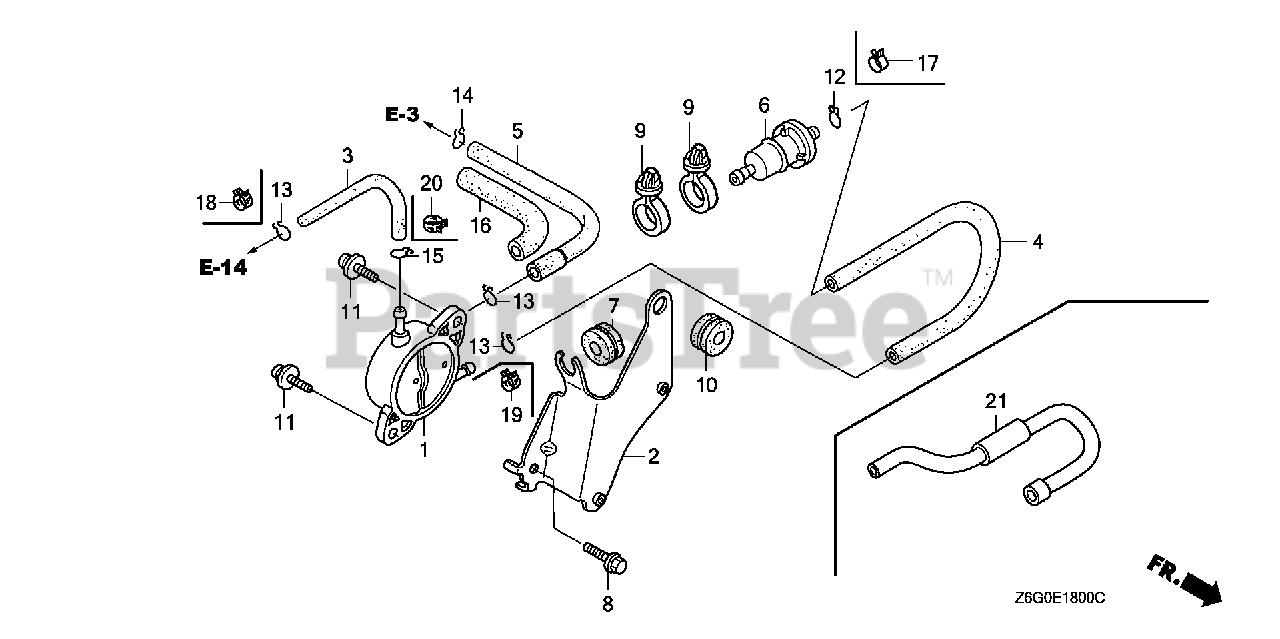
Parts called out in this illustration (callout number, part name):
1	PUMP ASSY., FUEL (MSDS)
2	STAY, FUEL PUMP
3	TUBE, FUEL (FKM)
5	TUBE, DIAPHRAGM
6	STRAINER, FUEL
7	GROMMET, RESERVE TANK
8	BOLT, FLANGE (6X14) (CT200)
9	CLIP, WIRE HARNESS
10	GROMMET, PUMP STAY
11	SCREW-WASHER (6X16)
13	CLIP, TUBE (B10)
14	CLIP, TUBE (B8)
16	BULK HOSE, VINYL (9X11X3000) (9X11X150)
17	CLAMP, TUBE (D8)
18	CLAMP, TUBE (D10)
19	CLAMP, TUBE (D8.5)
20	CLAMP, TUBE (D10)
21	TUBE B, FUEL (FKM)
